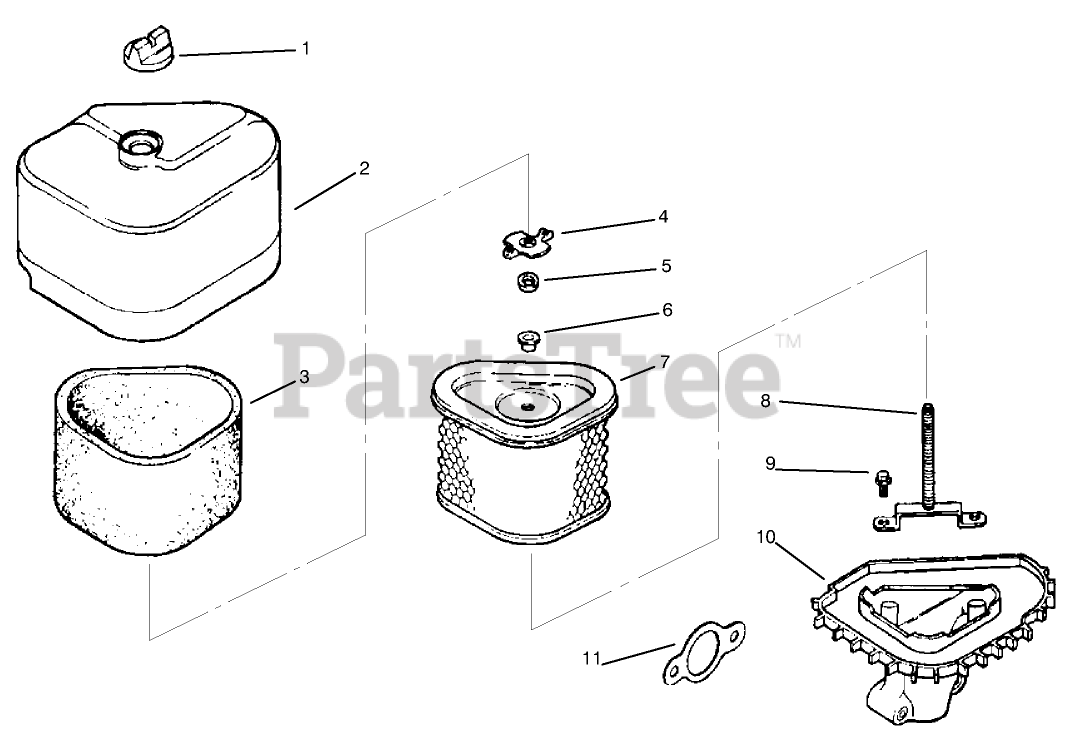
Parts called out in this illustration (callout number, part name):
1	Knob-Cover
2	Cover-Air Cleaner
3	Precleaner-Element
4	Wingnut
5	Washer
6	Grommet
7	Element-Air Cleaner
8	Stud-Mounting Plate
9	Screw
10	Base-Air Cleaner
11	Gasket-Air Cleaner
